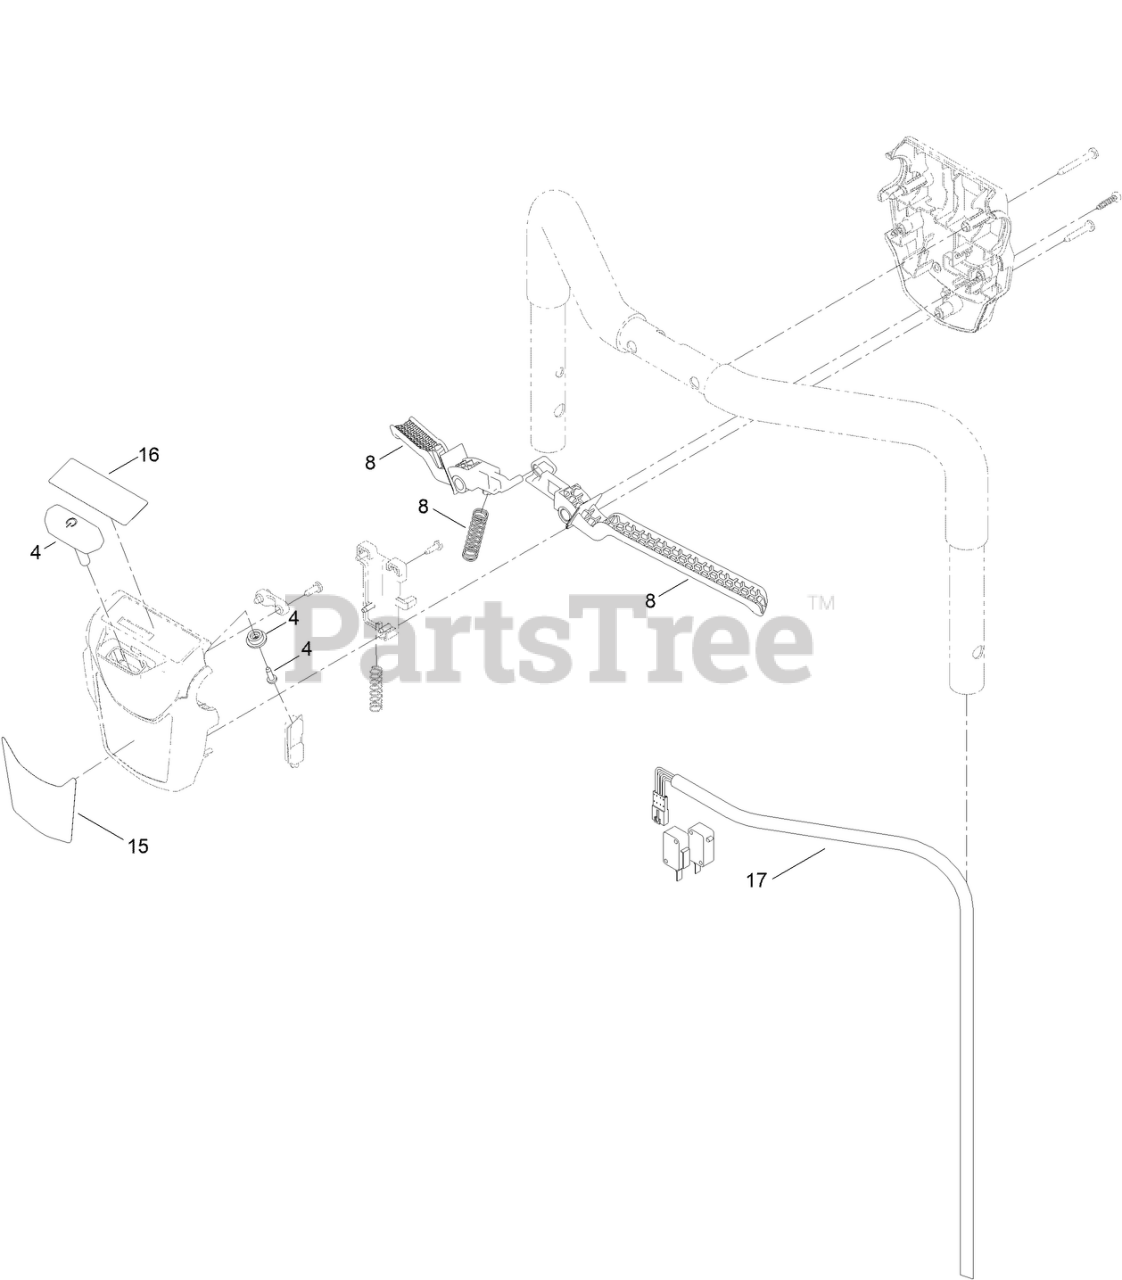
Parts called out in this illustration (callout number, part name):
4	TOP BUTTON KIT
8	UPPER LEVER KIT (43)
15	DECAL - VOLTA HANDLE
16	DECAL - BOOST KEY MAT
17	WIRING LOOM, PUSH
